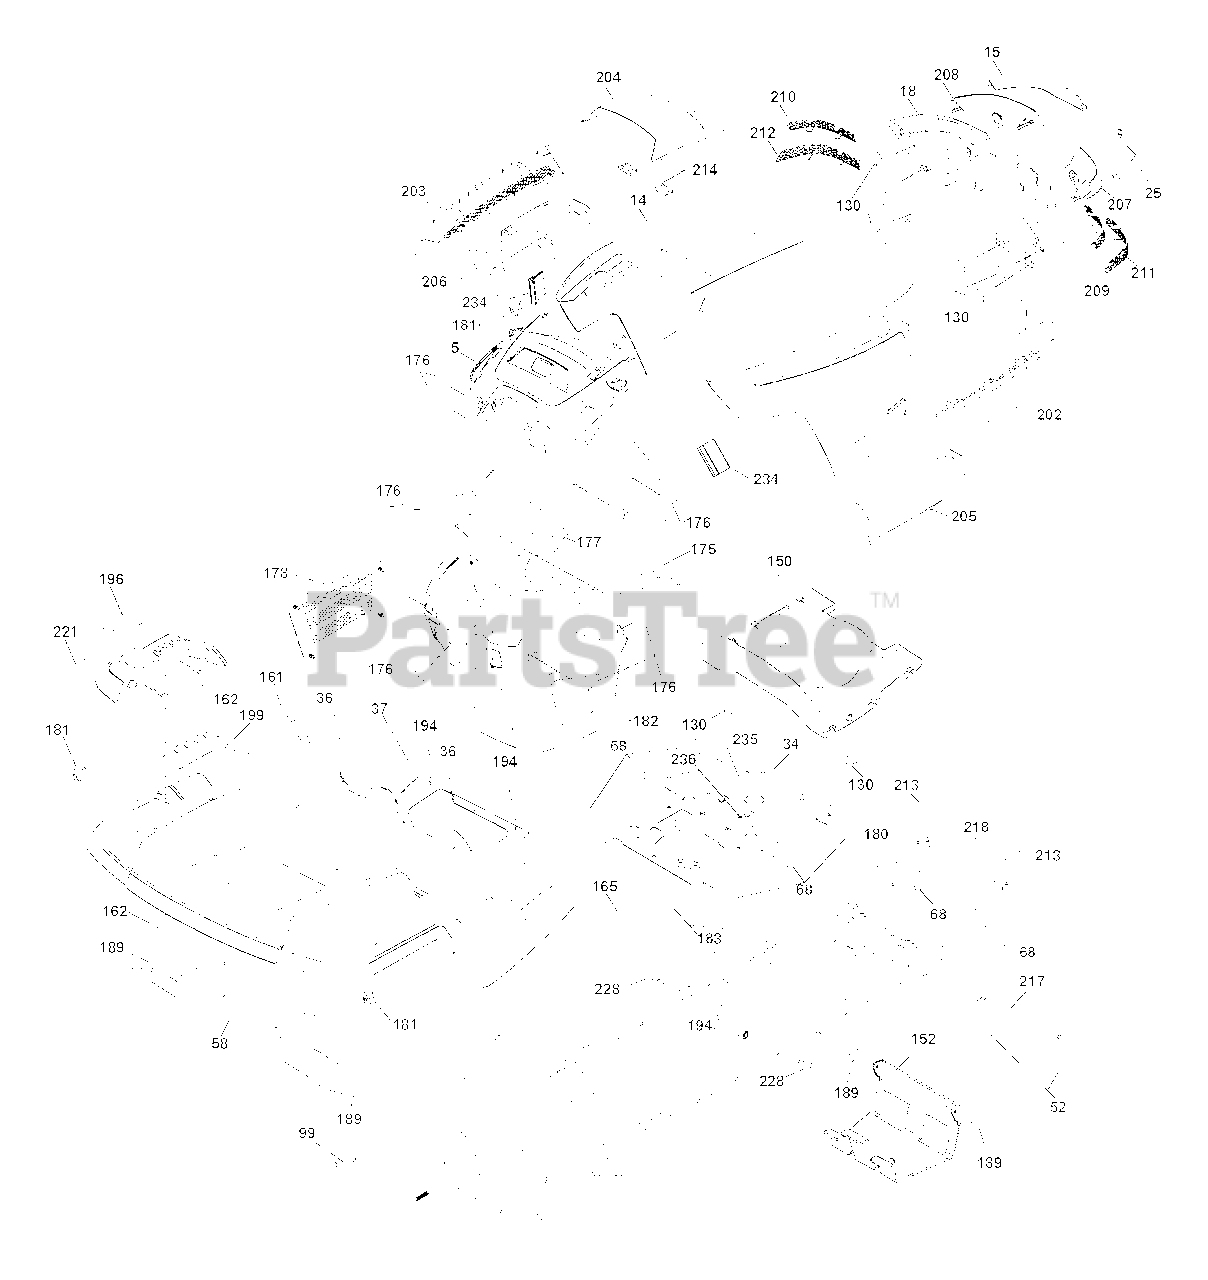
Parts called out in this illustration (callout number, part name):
14	Hood
18	Grille
34	Plate Engine
36	Screw 5/16-18 x 3/4
37	Fender
52	Nut Crown Lock 5/16-18
58	Bracket Fender
68	Screw 5/16-18 x 1/2
99	Rod Bypass Asm.
130	Screw 10 x 3/4 Single Lead Hex
150	Duct Heat Hood
152	Shield Browning/Debris
161	Console Fuel Window
162	Screw Hex Wsh Hi-Lo 1/4 x 1/2
165	Bracket Support Tank
175	Crossmember
176	Screw 10-24 x 5/8 Wshd Qdrx
177	Bushing Steering
178	Cargo Asm. Net
180	Chassis
181	Bushing Mtg. Fender Crgo.
182	Dash Lower
183	Bolt Fin Hex 5/16-18 UNC x 1-1/4
189	Screw 5/16-18 x 3/4
194	Nut Lock Hex Flange 5/16-18
196	Console Asm. Deck Lift
199	Plate Deck Lift
202	Vent Side Hood RH
203	Vent Side Hood LH
204	Vent Asm Hood Top
205	Skirt Hood Side RH
206	Skirt Hood Side LH
209	Insert Hex Top RH
210	Insert Hex Top LH
211	Insert Hex Bottom RH
212	Insert Hex Bottom LH
213	Bolt Hex Hd 5/16-18 unc x 3/4
214	Clip Retainer
217	Rod Pivot
221	Reflector LH
228	Stud Fastener
234	Bumper Hood
235	Spacer Fender
236	Nut Center Lock 5/16-18 UNC
